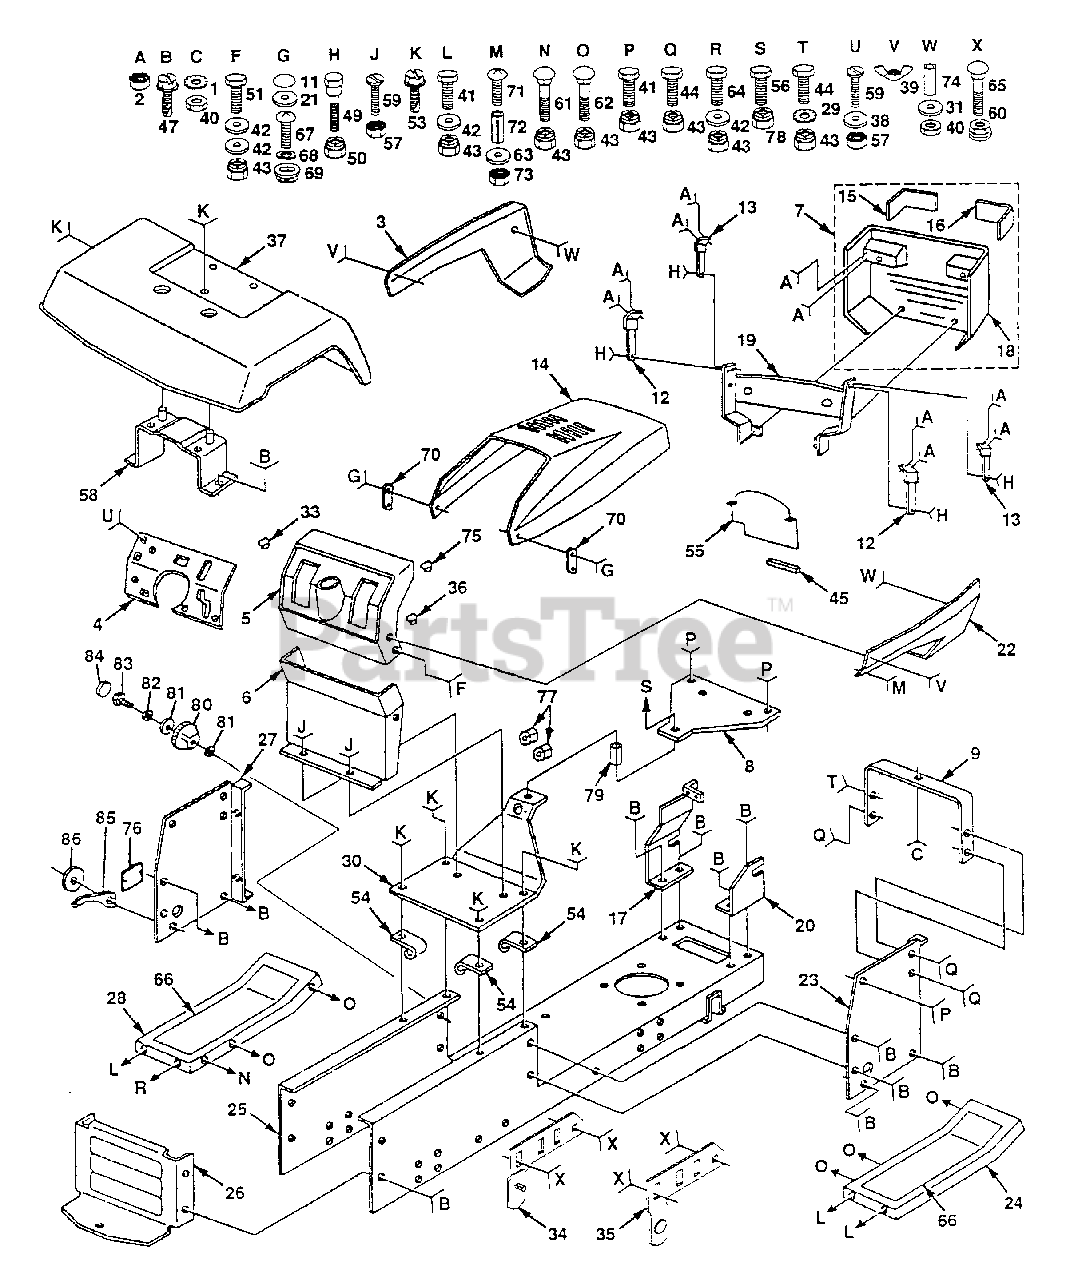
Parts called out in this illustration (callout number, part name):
1	Washer, Lock, External Tooth 1/4
2	Nut, Hex, Keps 1/4-20 UNC
3	Side Panel, LH
4	Plate, Dash
5	Dashboard
6	Dash, Lower
7	Grill Assembly
8	Plate, Battery Support
9	Support, Dash
11	Cap, Black
12	Strap Assembly, Hinge, Rear
13	Strap Assembly, Hinge, Front
15	Lens, Headlight, LH, Smoked
16	Lens, Headlight, RH, Smoked
17	Pivot Bracket Assembly, LH
18	Grille
19	Support Assembly, Grille
20	Pivot Bracket Assembly, RH
21	Washer, Cap
22	Side Panel, RH
23	Dash Panel, RH
24	Footrest, RH
25	Chassis 11 ga
26	Drawbar
27	Dash Panel, LH
28	Footrest, LH
29	Washer, Lock, External Tooth 3/8
31	Washer 9/32 x 3/4 x 16 Gauge
33	Plug, Button
34	Pivot Bracket Assembly, Rear, LH
35	Pivot Bracket Assembly, Rear, RH
36	Plug, Dome, Black
37	Fender
38	Washer 11/32 x 11/16 x 16 Gauge
39	Wing Nut, Plastic 1/4-20
40	Nut, Hex, Fin. 1/4-20 UNC
41	Bolt, Hex, Fin. 3/8-16 UNC x 3/4
42	Washer 13/32 x 13/16 x 12 Gauge
43	Nut, Crownlock 3/8-16 UNC
44	Bolt, Hex, Fin. 3/8-16 UNC x 1
45	Strip, Foam
47	Screw, Thd., Roll. 3/8-16 x 3/4
49	Bolt, Shoulder 1/4-20 UNC
50	Nut, Crownlock 1/4-20 UNC
51	Bolt, Hex, Fin. 3/8-16 UNC x 1
53	Screw, Thd., Roll. 3/8-16 x 1/2
54	Clip, Fuel Line
55	Baffle, Vertical
56	Bolt, Hex, Fin. 5/16-18 UNC x 2
57	Nut, Hex, Keps 5/16-18 UNC
58	Bracket Fender
59	Screw, Machine 5/16-18 UNC x 3/4
60	Locknut, Hex, with Washer Insert 3/8-16 UNC
61	Bolt, Carriage 3/8-16 UNC x 1
62	Bolt, Carriage 3/8-16 x 3/4
63	Washer 7/32 x 1/2 x 18 Gauge
64	Bolt, Hex. Fin. 3/8-16 UNC x 7/8
65	Bolt, Carriage 3/8-16 UNC x 1
66	Pad, Footrest
67	Screw, Machine, Cross Pan Head # 10-24 x 1 /2
68	Washer, Lock #10
69	Nut, Weld
70	Latch, Chute
71	Screw, Machine, Cross Pan Head 10-24 x 1-1 /4
72	Spacer, Split #10 x 3/4
73	Nut, Hex. Keps #10-24 UNC
74	Spacer 17/64 x 1/2 x 3/8
76	Cover Access
77	Bushing Snap Split
78	Nut Crownlock 5/16-18
79	Spacer Split
80	Scale Ind Height
81	Washer 11/32 x 1-1/2 x 10 Ga.
82	Washer Lock Hvy Hlcl Spr. 5/16
83	Bolt Hex 5/16-18 x 1
85	Pointer Height Indicator
86	Washer Nylon
